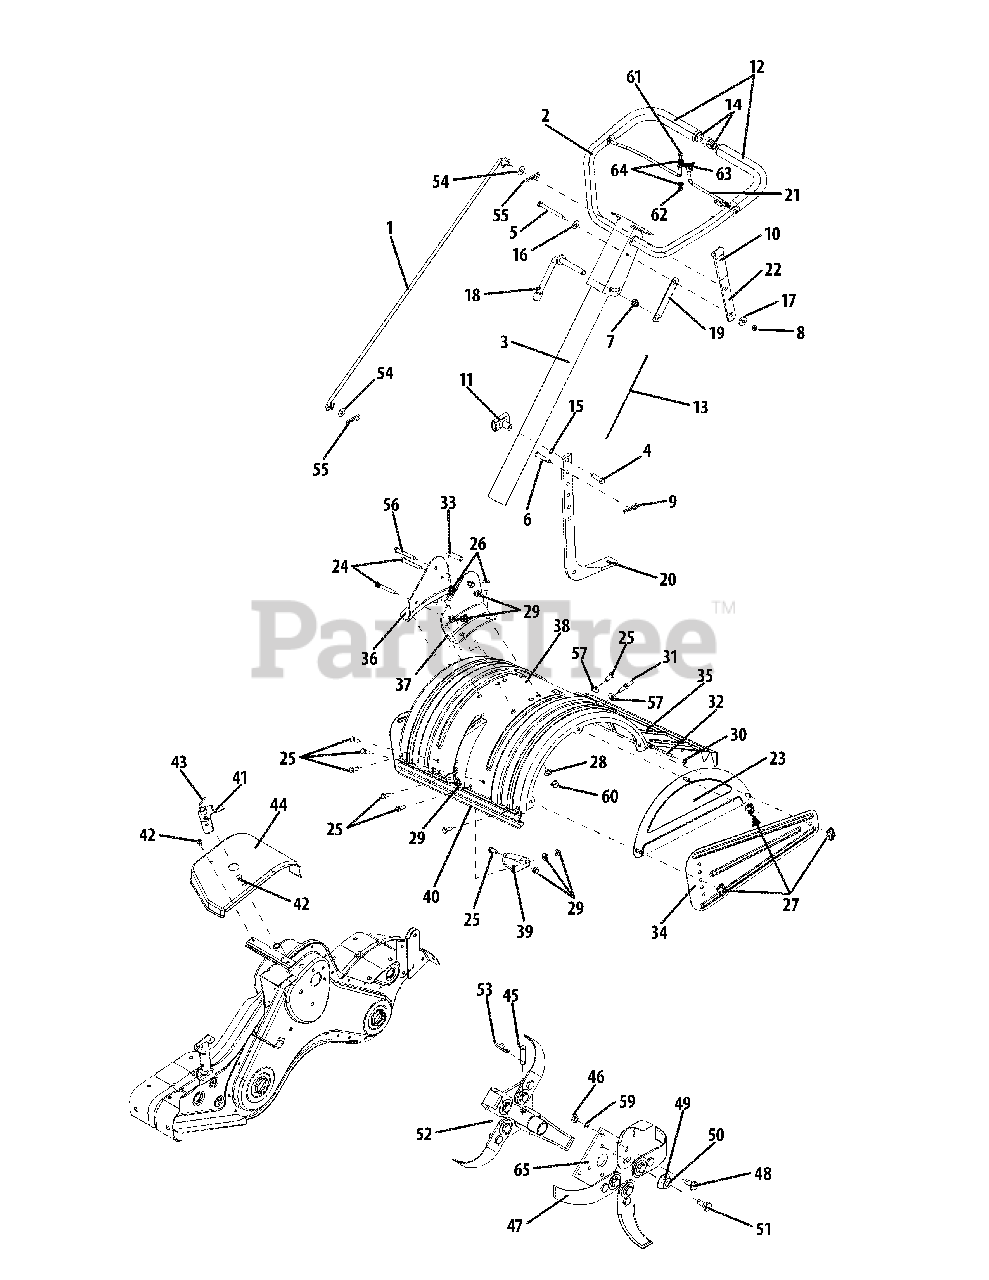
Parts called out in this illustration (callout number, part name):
1	Shift Rod
4	Hex Screw, 3/8-16 x 1.25
5	Hex Screw, 5/16-18 x 3.25
6	Clevis Pin,3/8 -1.62
7	Flange Lock Nut, 3/8 -24
8	Hex Lock Nut, 5/16-18
9	Cotter Pin
11	T-Knob
12	Foam Grip
13	Cable Tie
15	Flat Washer, 3/8 ID x .620 OD
16	Bell Washer, .340 ID x .872 OD
17	Shoulder Spacer
18	Handle Adjustment Crank
19	Hex Nut Retainer Bracket
24	Hex Cap Screw, 5/16-18 x 2.75
25	Hex Cap Screw, 5/16-18 x .750
26	Carriage Bolt, 3/8 -16 x 1.0
27	Wing Nut
28	Lock Washer, 3/8
29	Flange Nut, 5/16-18
30	Cap Nut
31	Hex Screw, 5/16-18 x .75"
33	Spacer, .322 x .625 x 2.0
41	Shift Crank Assembly
42	Screw, 1/4-14 x .625
43	Spiral Pin, 3/16 x 1.0
46	Hex Nut, 3/8 -24
48	Shoulder Bolt
49	Flat Washer, .51" ID x 1.50" OD
50	Bell Washer, .515" ID x 1.14" OD
51	Shoulder Bolt
53	Internal Cotter Pin
54	Rubber Washer
55	Cotter Pin
56	Hex Screw, 3/8-16 x 2.75"
57	Flat Washer
58	Flange Nut, 3/8 -16
59	Lock Washer
60	Hex Nut, 3/8-16
61	Truss Screw, 1/4-20 x .65
62	Hex Lock Nut 1/4-20
63	Battery Hose Clamp, 5/16
64	Flat Washer, .260 ID x .720 OD
